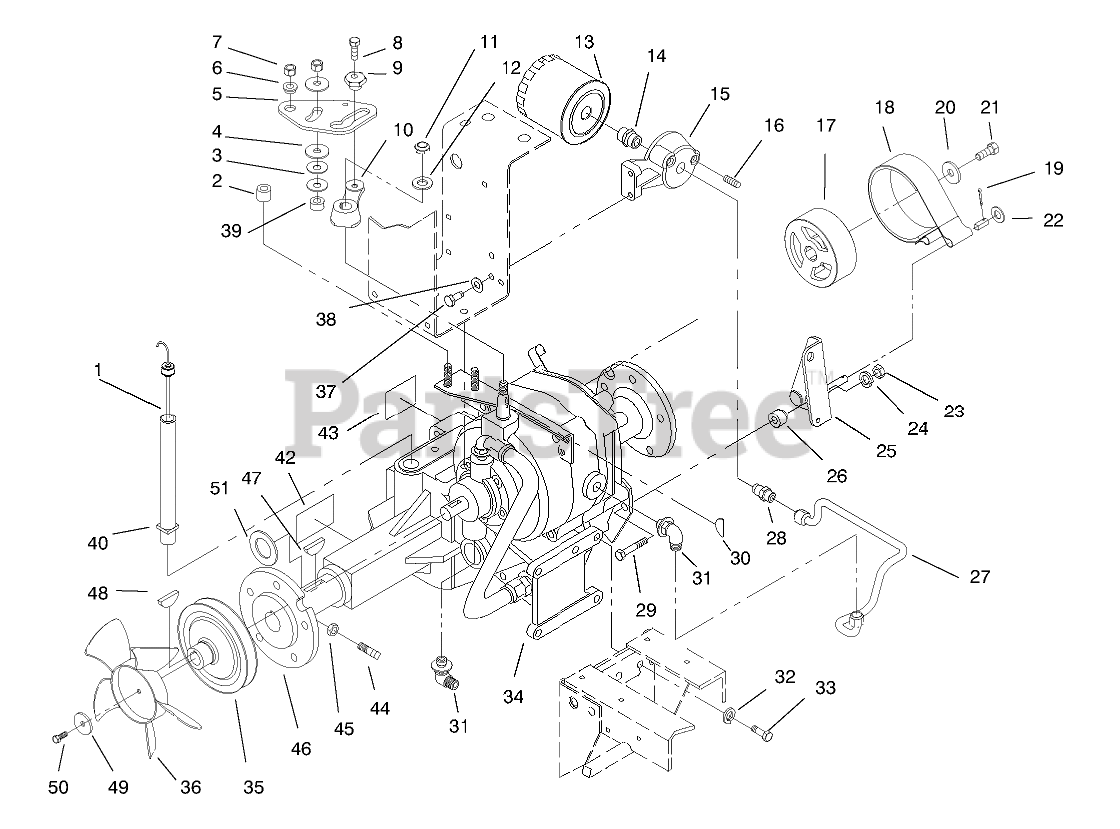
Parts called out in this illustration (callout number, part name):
1	ASSY DIPSTICK (BLACK)
2	Spacer-Pivot
3	WASHER-SPRING DISC
4	FRICTION WASHER
5	CAM-SPEED CONTROL (NS)
6	CAM-SPACER
8	Screw-HH
10	ARM-SPEED CONTROLB
11	NUT-LOCK, NI
12	WASHER-FLAT
13	OIL FILTER ASM
14	FITTING
15	BASE-FILTER
17	DRUM-BRAKE
18	ASSY-BRAKE BAND
19	PIN-COTTER
20	WASHER
21	SCREW-HH, LOCK
22	WASHER-FLAT
23	NUT-LOCK, NI
24	WASHER-FLAT
25	Pivot Arm-Brake
26	BUSHING-BRAKE PIVOT
27	ASS'Y-TUBE FILTER
28	FITTING
29	SCREW-HH
30	KEY-WOODRUFF
31	ELBOW
32	WASHER-LOCK
33	SCREW-HH
35	PULLEY
36	NYLON FAN-L-CW
37	SCREW-HH
38	WASHER-LOCK
39	SPACER-FRICTION
40	NIPPLE-TRANS FILL
42	DECAL - DANGER
43	DECAL-UNIDRIVE
44	SCREW-SET, SQH
45	NUT-JAM
46	HUB-WHEEL
47	KEY-WOODRUFF
48	KEY-WOODRUFF
49	WASHER
50	SCREW-HEX HD CAP
51	WASHER-THRUST
